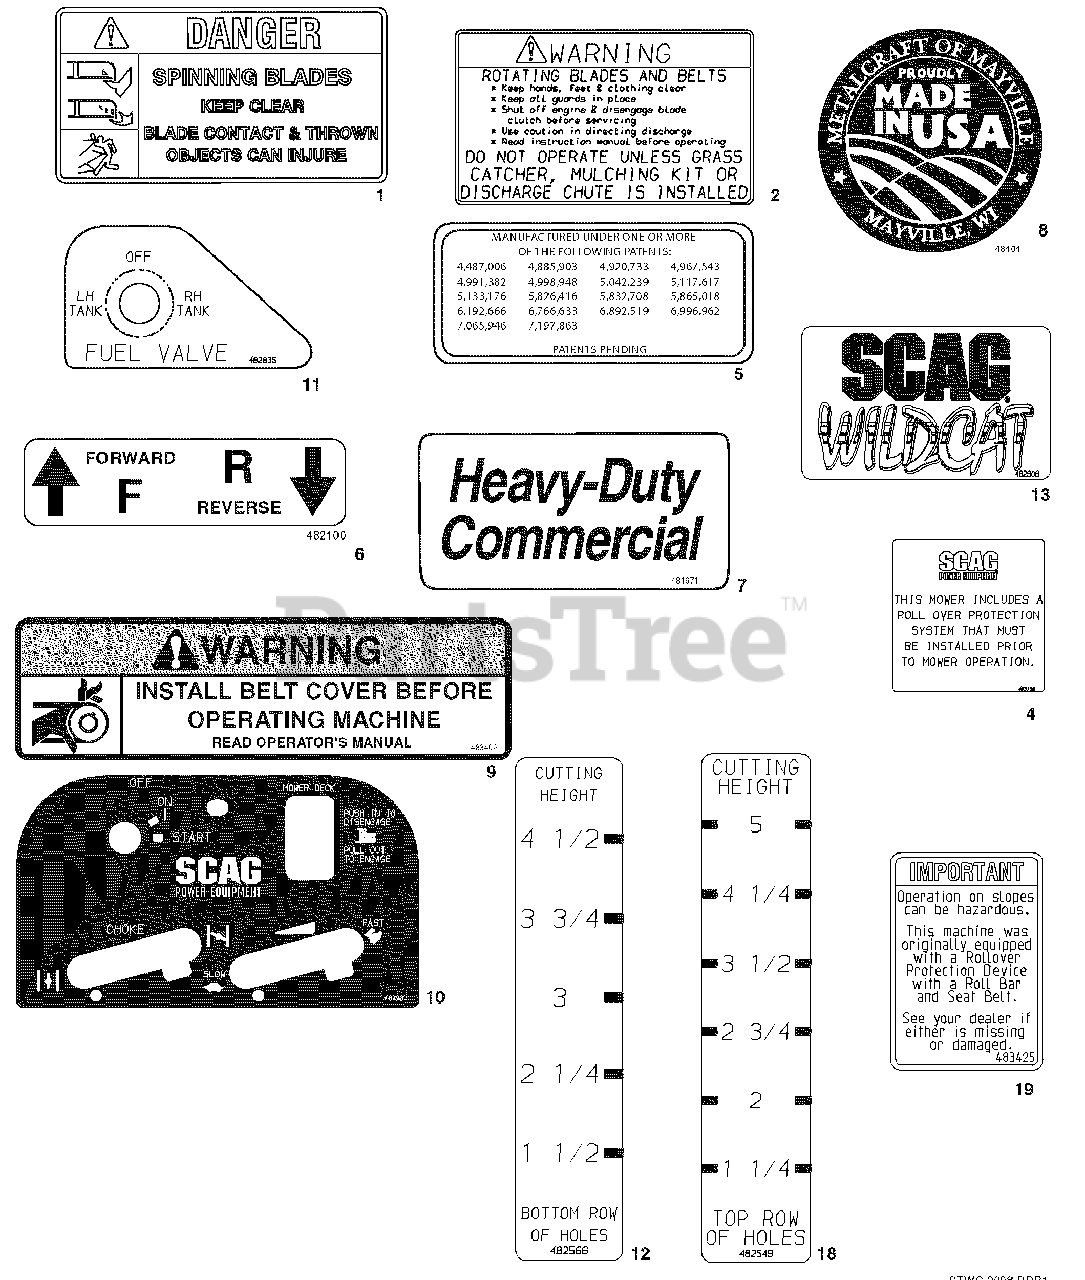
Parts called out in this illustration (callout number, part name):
1	Decal, Danger-Spinning Blades
2	Decal, Warning-Rotating Blades
4	Decal, ROPS
5	Decal, Patents
6	Decal, Traction Control
7	Decal, Heavy Duty Commercial
8	Decal, Metalcraft - Made in USA
9	Decal, Belt Cover
10	Decal, Instrument Panel
11	Decal, Fuel Valve Position
12	Decal, Cutting Height Bottom Row of Holes
13	Decal, Wildcat
18	Decal, Cutting Height Top Row of Holes
19	Decal, ROPS
